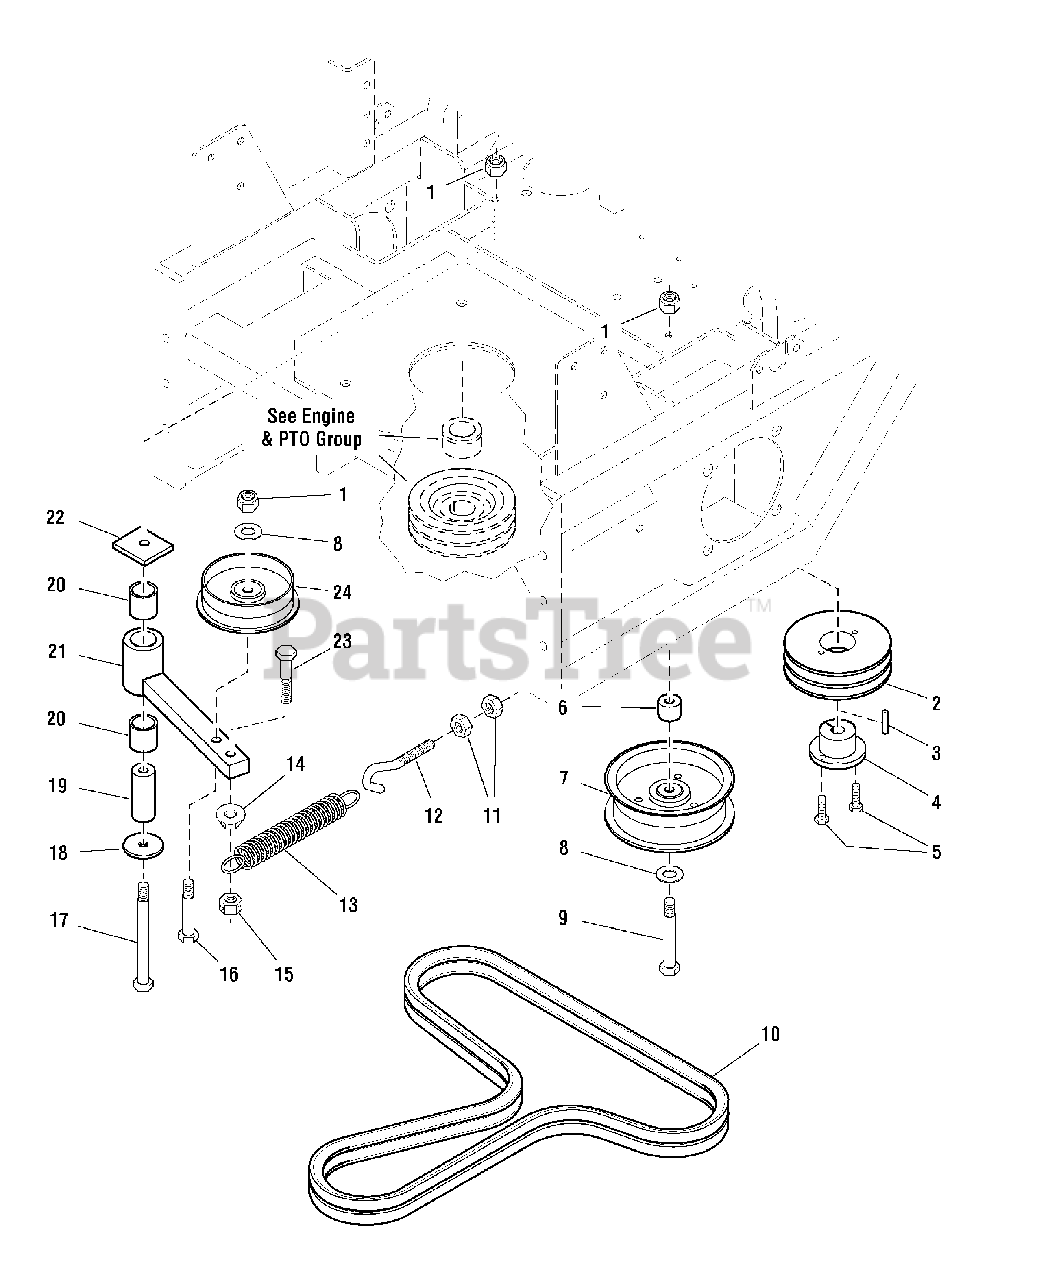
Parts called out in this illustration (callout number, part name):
1	NUT, Hex, Nylon Lock, 3/8-16
2	PULLEY, Pump Drive
3	KEY, 5mm x 25mm
4	BUSHING, Tapered Hub
5	BOLT, 1/4-20 X 1", GD
6	SPACER, .39 x 1.00 x .79
7	PULLEY, Idler
8	WASHER, 3/8
9	CAPSCREW, Hex Hd, 3/8-16 x 2-3/4
10	BELT, BANDED A-SEC, 64.76EL, POLY, RAW EDGE
11	NUT, Hex, 3/8-16
12	SCREW HOOK, 3/8-16 x 4-1/4
13	SPRING, Extension, Swivel End
14	NUT, Hex, Serrated Flange, 3/8-16
15	NUT, Hex, Side Lock, 3/8-16
16	CAPSCREW, Hex Hd, 3/8-16 x 2-1/4
17	CAPSCREW, Hex Hd, 3/8-16 x 4
18	WASHER, 3/8 x 1-3/4
19	SHAFT, Idler Pivot
20	BUSHING, Brass
21	WELD, ARM, PUMP DRIVE IDLER - BLK
22	SPACER, Idler Pivot
23	CAPSCREW, Hex Hd, 3/8-16 x 1-3/4
24	PULLEY, Idler (Single Flange)
